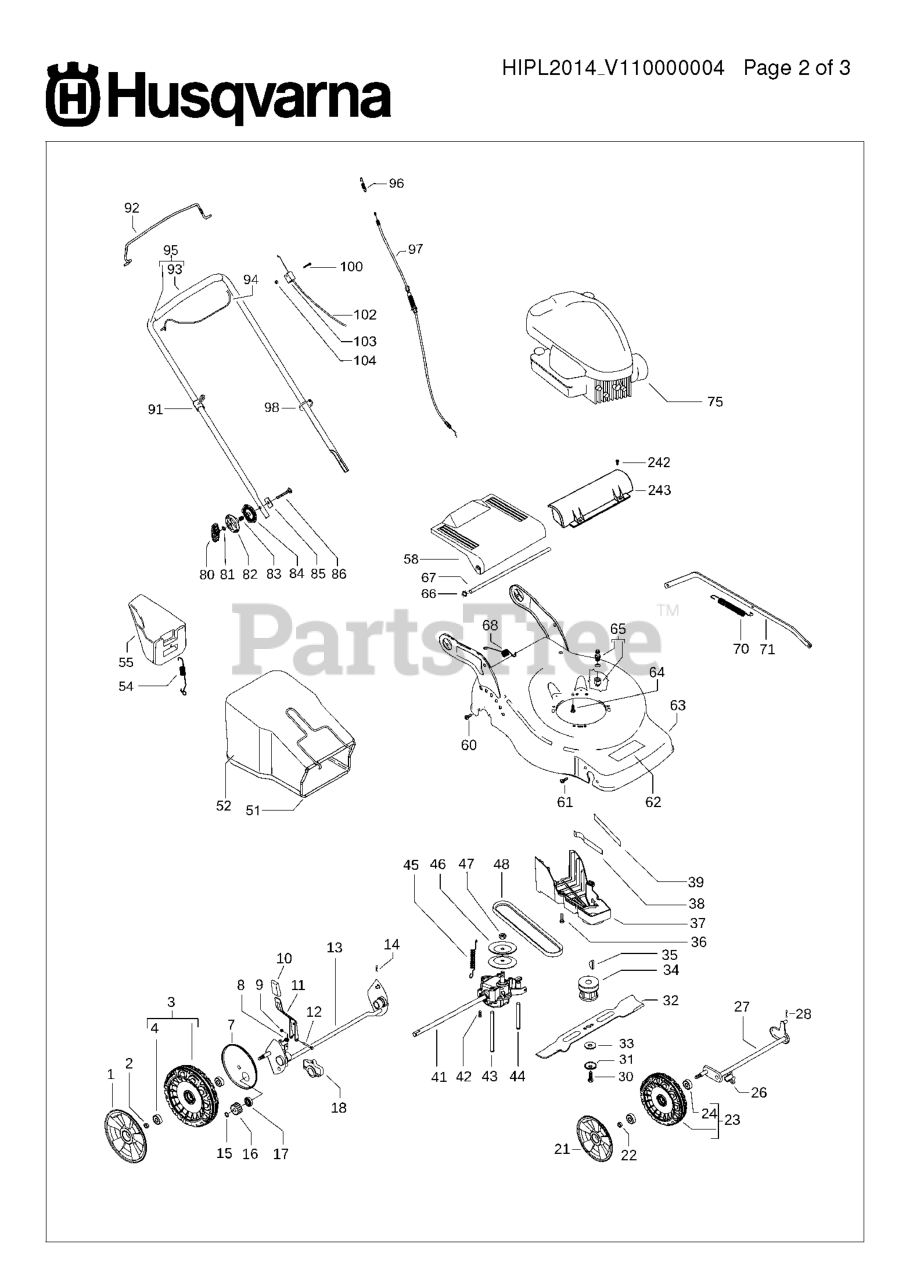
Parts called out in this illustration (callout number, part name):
32	MOWER BLADE COMBI
34	BLADE SUPPORT
102	BRAKE WIRE
